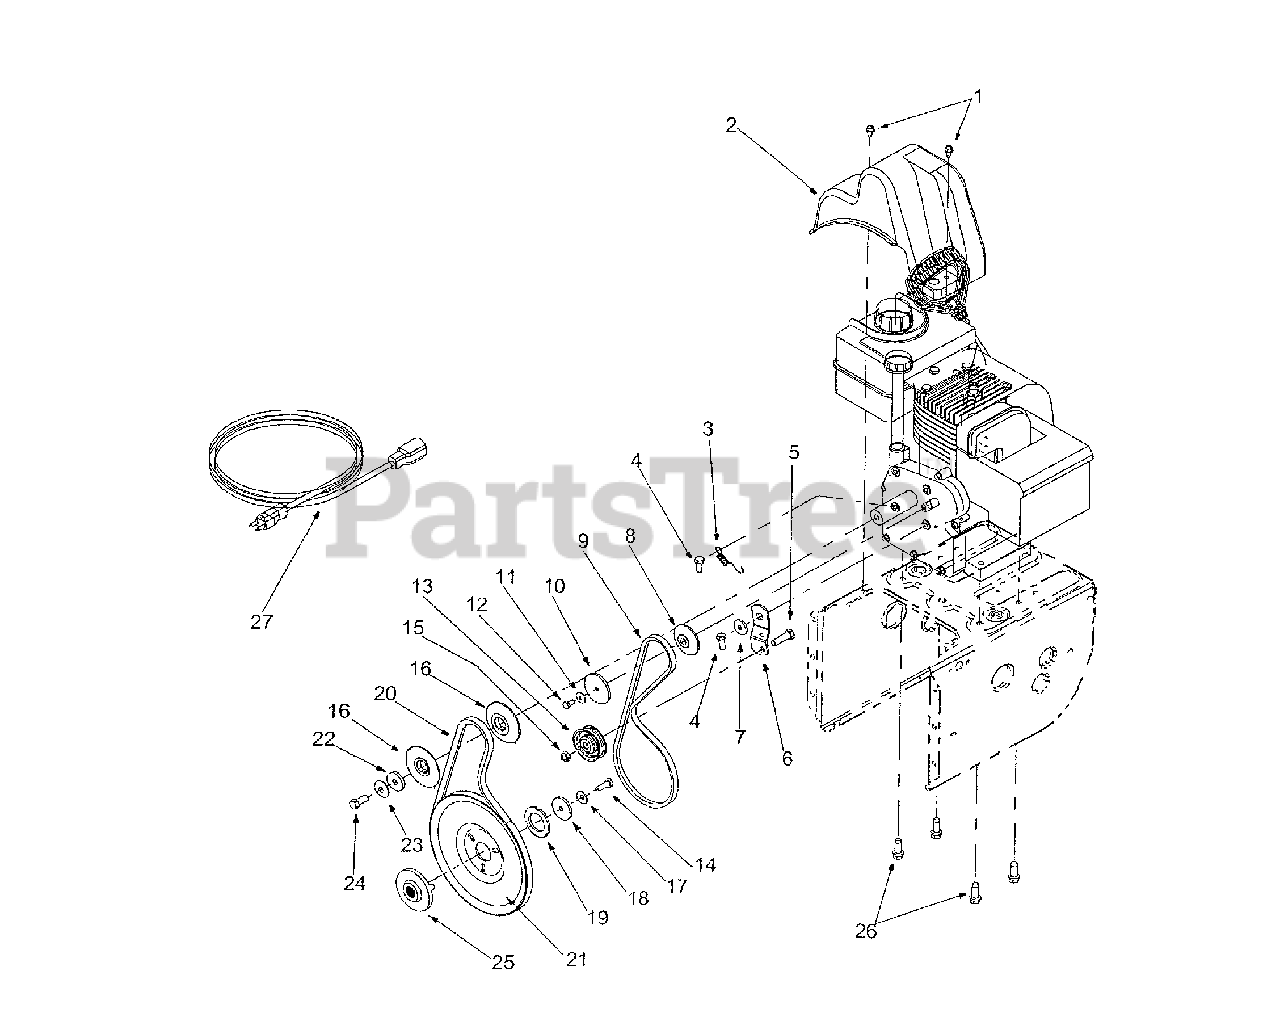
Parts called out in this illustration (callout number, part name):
1	Hex Washer Screw 1/4-20 x.5
2	Belt Cover
3	Extension Spring
4	Hex Screw 5/16-24 x .75
5	Hex Cap Screw 3/8-16 x 1.25
8	Pulley Half
9	V-Belt
10	Pulley Half
11	Bell Washer
12	Hex Cap Screw 1/4-28 x .50
13	Flat Idler
14	Lock Cap Screw 5/16-24
15	Lock Jam Nut 3/8-16
16	Pulley Half
17	Bell Washer
18	Flat Washer
19	Washer
20	Belt
21	Auger Pulley
22	Flat Washer
23	Bell Washer
24	Hex Cap Screw 3/8-24
25	Pulley
26	Hex Washer Screw 3/8-16 x 1.0
27	Extension Cord
